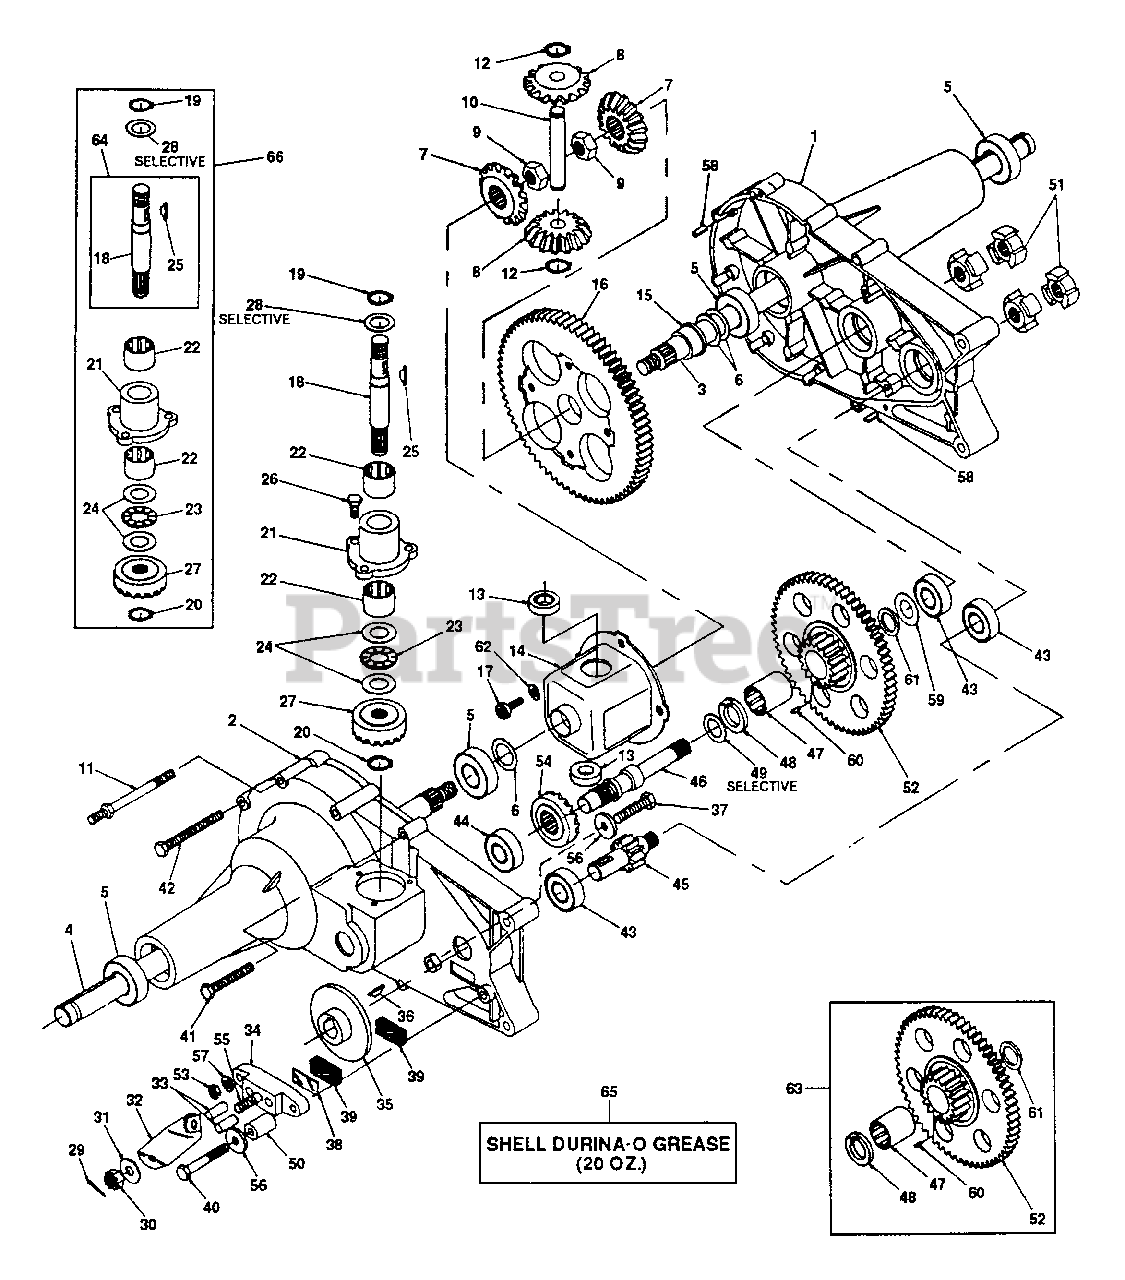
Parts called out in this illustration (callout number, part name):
1	Housing, Half L.H.
2	Housing, Half R.H.
5	Bearing, Ball
6	Washer, Flat 3/4 x 1-1/8 x .030
7	Gear, Miter
8	Gear, Miter
9	Nut, Hex Jam w/Patch 1/2-20
10	Shaft, Cross
11	Screw, Stud
12	Snap, Ring
13	Bearing, Thrust
14	Housing Assembly, Differential
15	Bearing, Flange
16	Gear, Differential 72 Tooth
17	Bolt, Torx Head 1/4-28 x 5/8"
18	Shaft, Input
19	Snap, Ring
20	Retaining Ring 7/16"
21	Housing, Input Bearing
22	Bearing, Needle
23	Bearing, Thrust
24	Washer, Flat 5/8 x 1-1/8 x .030
25	Key, Hi-Pro 3/32 x 5/8
26	Screw, Hex W/Patch 1/4-20 x 3/4
27	Gear, Input Pinion 17 Tooth
28	Washer, Flat .62 x 1 x .05
28	Washer, Flat .62 x 1.125 x .060
28	Washer, Flat .62 x 1 x .040
29	Pin, Cotter
30	Nut, Castle 5/16-24
31	Washer, Flat .343 x .88 x .062
32	Arm, Brake Actuator
33	Pin, Brake Actuating
34	Brake, Yoke
35	Disc, Brake
36	Key, Hi-Pro 3/16 x 5/8"
37	Screw, Hex 1/4-20 x 1.50
38	Plate, Puck
39	Puck, Brake
40	Screw, Hex w/Patch 1/4-20 x 2.00
41	Screw, Hex Self-Tap 1/4-20 x 2.00
42	Screw, Hex Self-Tap 1/4-20 x 3.00
43	Bearing, Ball
44	Bearing, Ball
45	Shaft, Pinion W/11 Tooth Gear
46	Shaft, Drive
47	Bearing, Needle
48	Bronze Thrust Brg. 5/8 x 1-1/4 x 7/64
49	Washer, Flat .62 x 1.0 x .050
49	Washer, Flat .62 x 1.0 x .040
50	Spacer
52	Gear, 60 and 17 Tooth
53	Nut, Hex 1/4-20
54	Gear. Drive Pinion 17 Tooth
55	Bolt, Square Head
56	Washer 15/16 x .265 x .125
57	Washer, Spring Lock 1/4"
58	Pin, Roll 3/16" x 1/2"
59	Washer, Flat .62 x 1.0 x .030
60	Pin, Dowel 3/32 x 1/4
61	Seal, Grease
62	Washer, Head Spring Lock 1/4"
63	Assembly, Gear, Reduction
64	Assembly, Shaft, Input
65	Shell Durina-O Grease (20 oz.)
66	Kit, Input Shaft
